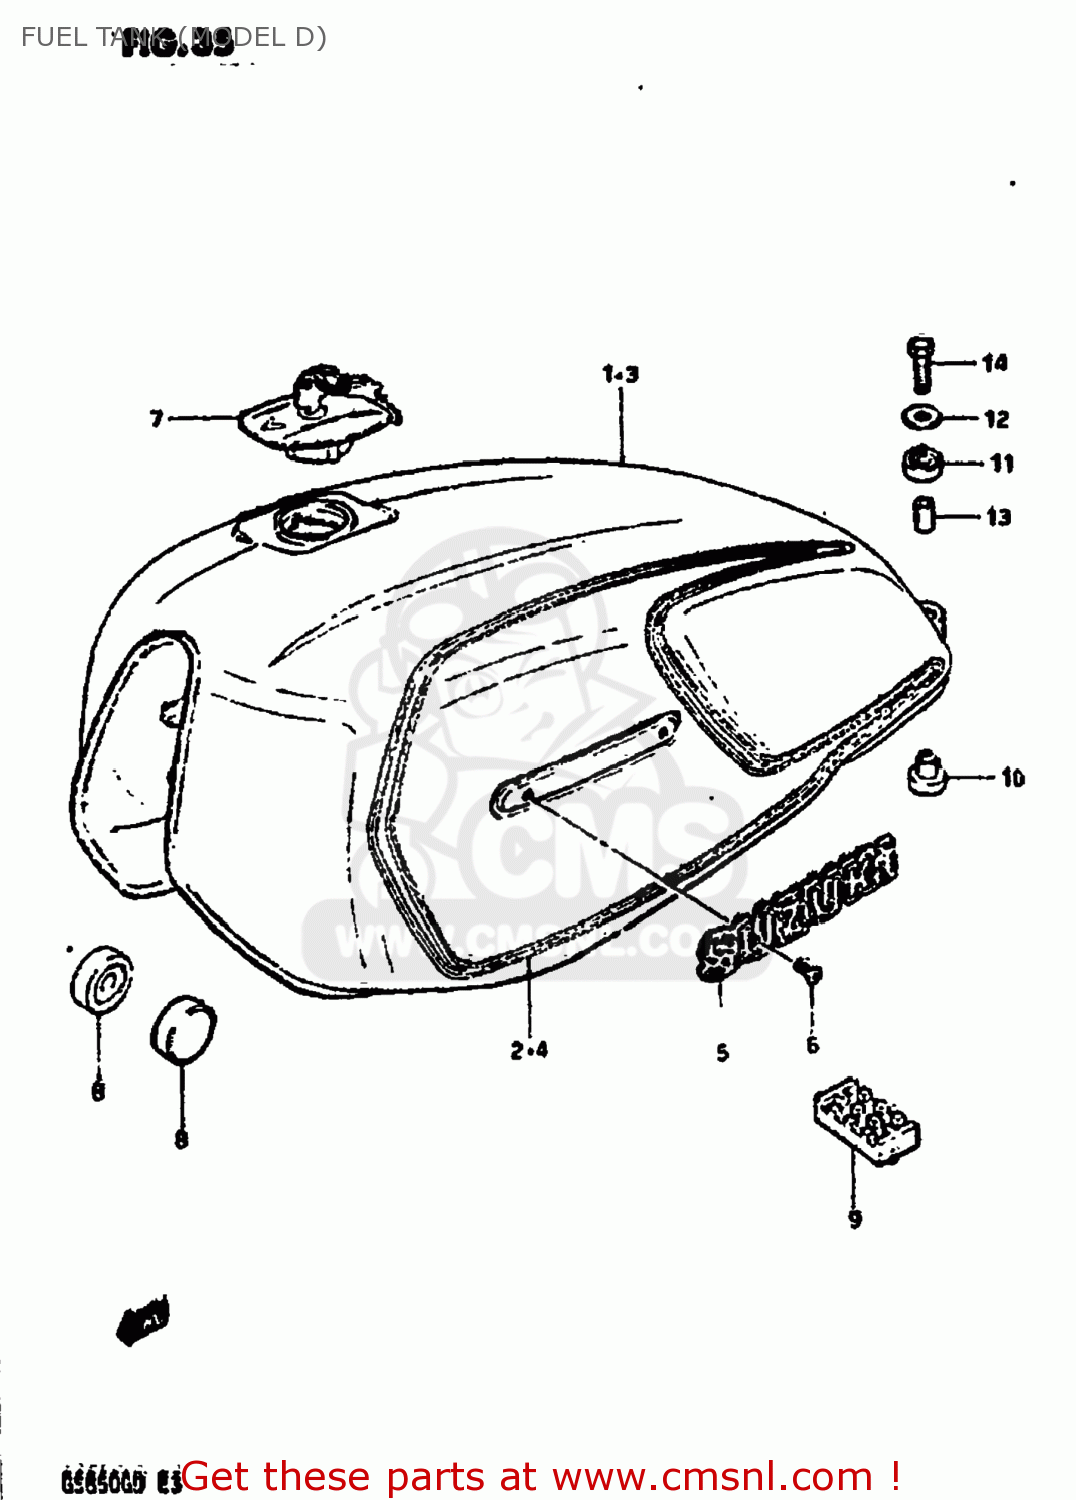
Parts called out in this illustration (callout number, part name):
1	TANK ASSEMBLY,FUEL
2	TAPE SET,FUEL TANK
3	TANK ASSEMBLY,FUEL
4	TAPE SET,FUEL TANK
5	EMBLEM
6	SCREW 3X6
7	CAP SET,FUEL TANK
8	CUSHION
9	CUSHION,FUEL TANK
10	CUSHION
11	CUSHION
12	WASHER (6.5X24X1.6)
13	SPACER (6.4X9X21.5)
14	BOLT
